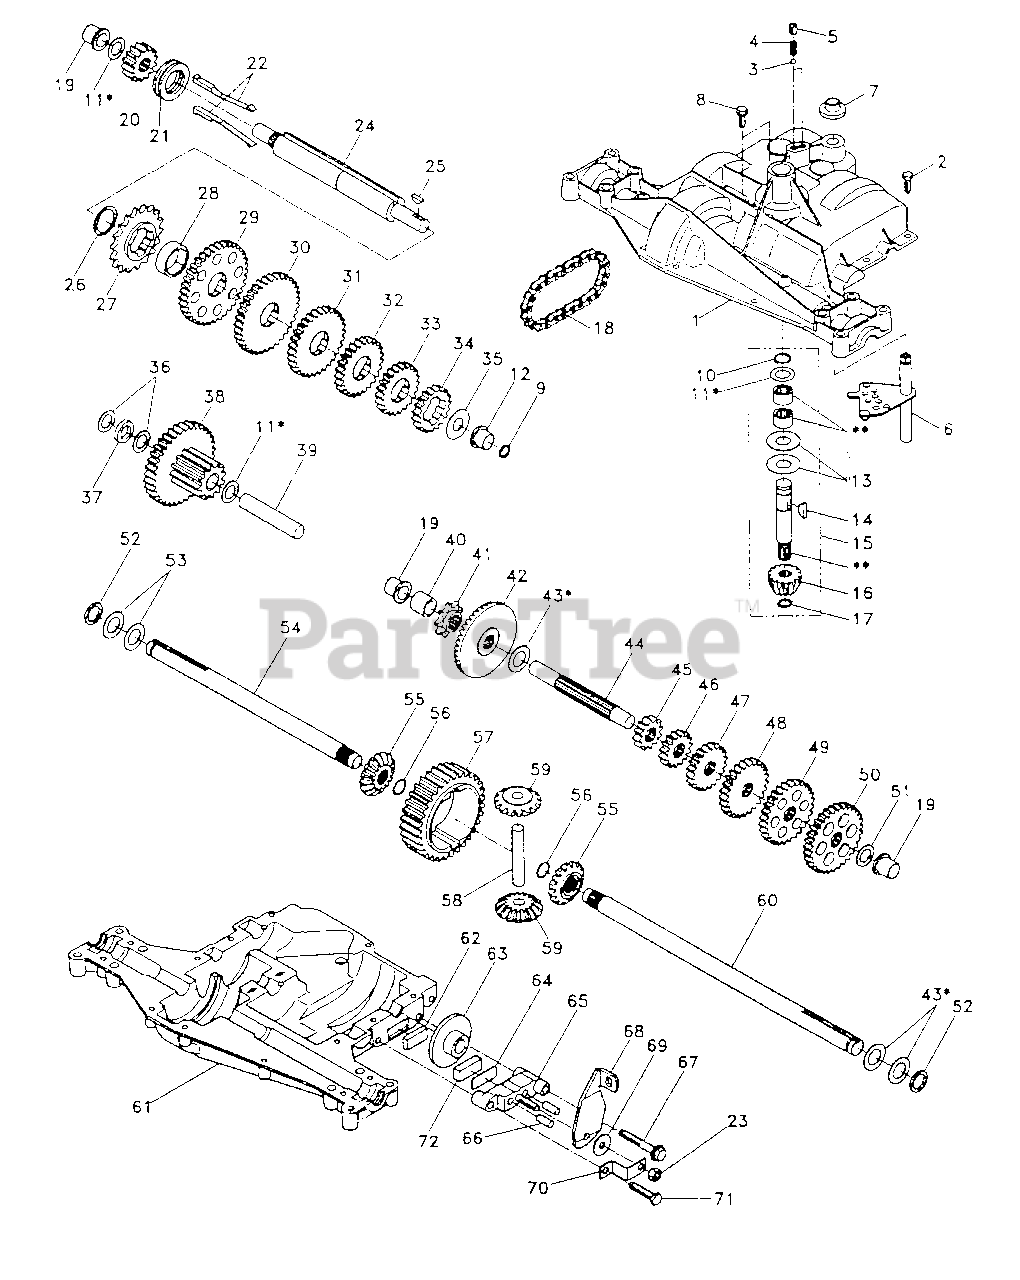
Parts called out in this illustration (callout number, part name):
1	Housing, Upper
2	Screw, Self-Tapping, Large 1/4-20 x .734
3	Ball, Detent (AYP part number)
4	Spring, Detent
5	Screw, Set
6	Kit, Shifter Assembly (AYP part number)
7	Boot, Shifter
8	Screw, Tapping w/Sealer
9	Square Ring
10	Ring, Retaining
11	Assembly, Kit, Shim .625 Shaft
12	Bearing, Flange
13	Washer, Plain .632 x 1.38 x .046
14	Key, Woodruff, #9
15	Assembly, Kit, Input Shaft (AYP part number)
16	Pinion, Bevel, 14 Teeth (AYP part number)
17	Ring, Retaining
18	Chain, 24 Pitches
19	Bearing, Flange
20	Gear, Spur, 14 Teeth
21	Collar, Clutch
22	Assembly, Kit, Clutch Keys
23	Locknut 5/16-24
24	Shaft, Intermediate
25	Key, Woodruff, #61
26	Ring, Retaining
27	Sprocket, 18 Teeth
28	Spacer
29	Gear, Spur, 37 Teeth
30	Gear, Spur, 35 Teeth (AYP part number)
31	Gear, Spur, 30 Teeth (AYP part number)
32	Gear, Spur, 25 Teeth
33	Gear, Spur, 22 Teeth
34	Gear, Spur, 19 Teeth
35	Washer, Plain .640 x 1.37 x .061
36	Washer, Plain .632 x 1.00 x .026
37	Spacer .630 x 1.00 x .169
38	Assembly, Gear, Combination of 12 Teeth and 35 Teeth
39	Shaft, Idler
40	Spacer .635 x .875 x .755
41	Sprocket, 9 Teeth
42	Gear, Bevel, 42 Teeth
43	Assembly, Kit, Shim .750 Shaft
44	Shaft, Drive
45	Gear, Spur, 12 Teeth (AYP part number)
46	Gear, Spur, 15 Teeth (AYP part number)
47	Gear, Spur, 20 Teeth (AYP part number)
48	Gear, Spur, 25 Teeth
49	Gear, Spur, 28 Teeth
50	Gear, Spur, 31 Teeth
51	Washer, Plain .632 x 1.00 x .060
52	Washer, Neoprene
53	Washer, Plain .758 x 1.25 x .031
54	Axle, L.H. (AYP part number)
55	Gear, Miter, 15 Teeth
56	Ring, Retaining
57	Gear, Spur, 32 Teeth (AYP part number)
58	Shaft, Cross
59	Gear, Miter, 15 Teeth
60	Axle, R.H. (AYP part number)
61	Housing, Lower
62	Puck, Friction
63	Disc, Brake
64	Spacer
65	Jaw, Brake
66	Pin, Dowel
67	Screw, Self-Tapping, Large 5/16-18 x 2.25
68	Lever, Actuating
69	Washer, Plain .321 x 1.00 x .055
70	Bracket, Anti-Rotation
71	Screw, Self-Tapping, Large 5/16-18 x 1.44
72	Puck, Friction
73	Grease (AYP part number)
